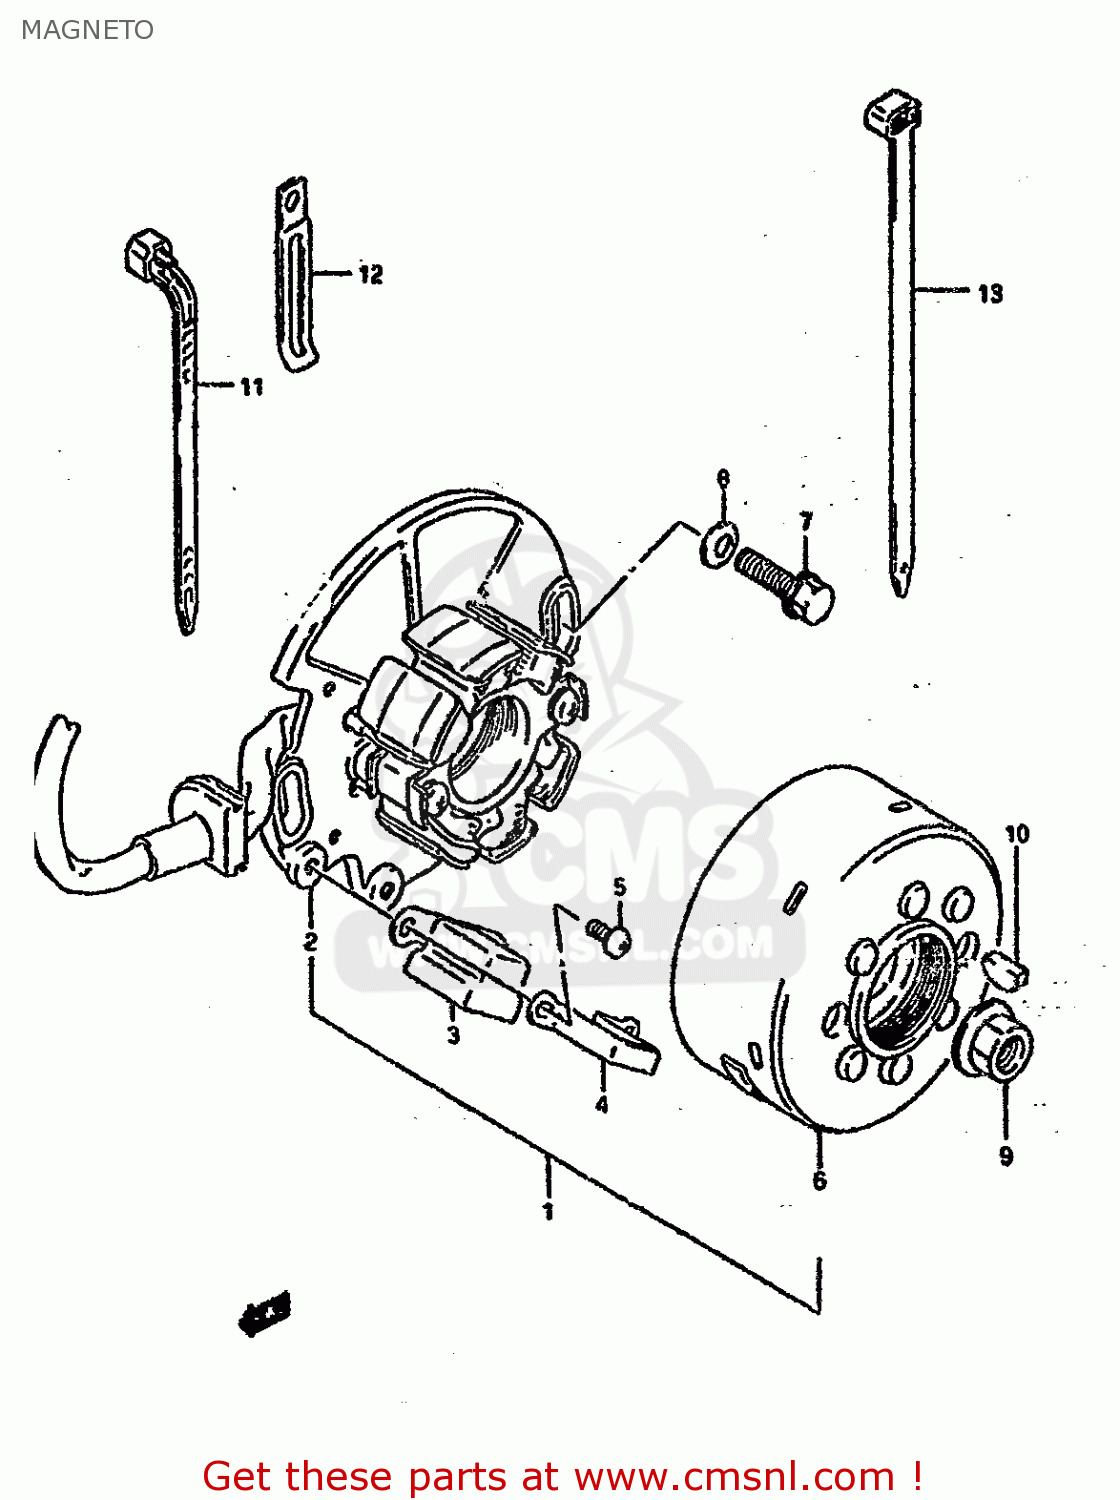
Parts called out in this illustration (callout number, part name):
1	MAGNETO ASSEMBLY
2	STARTER ASSY
3	COIL ASSEMBLY,PICK-UP
4	HOLDER,PICK UP COIL
5	SCREW
6	ROTOR
7	BOLT
8	WASHER
9	NUT
10	KEY
11	CLAMP(L:125)
12	CLAMP
13	CLAMP L:165
